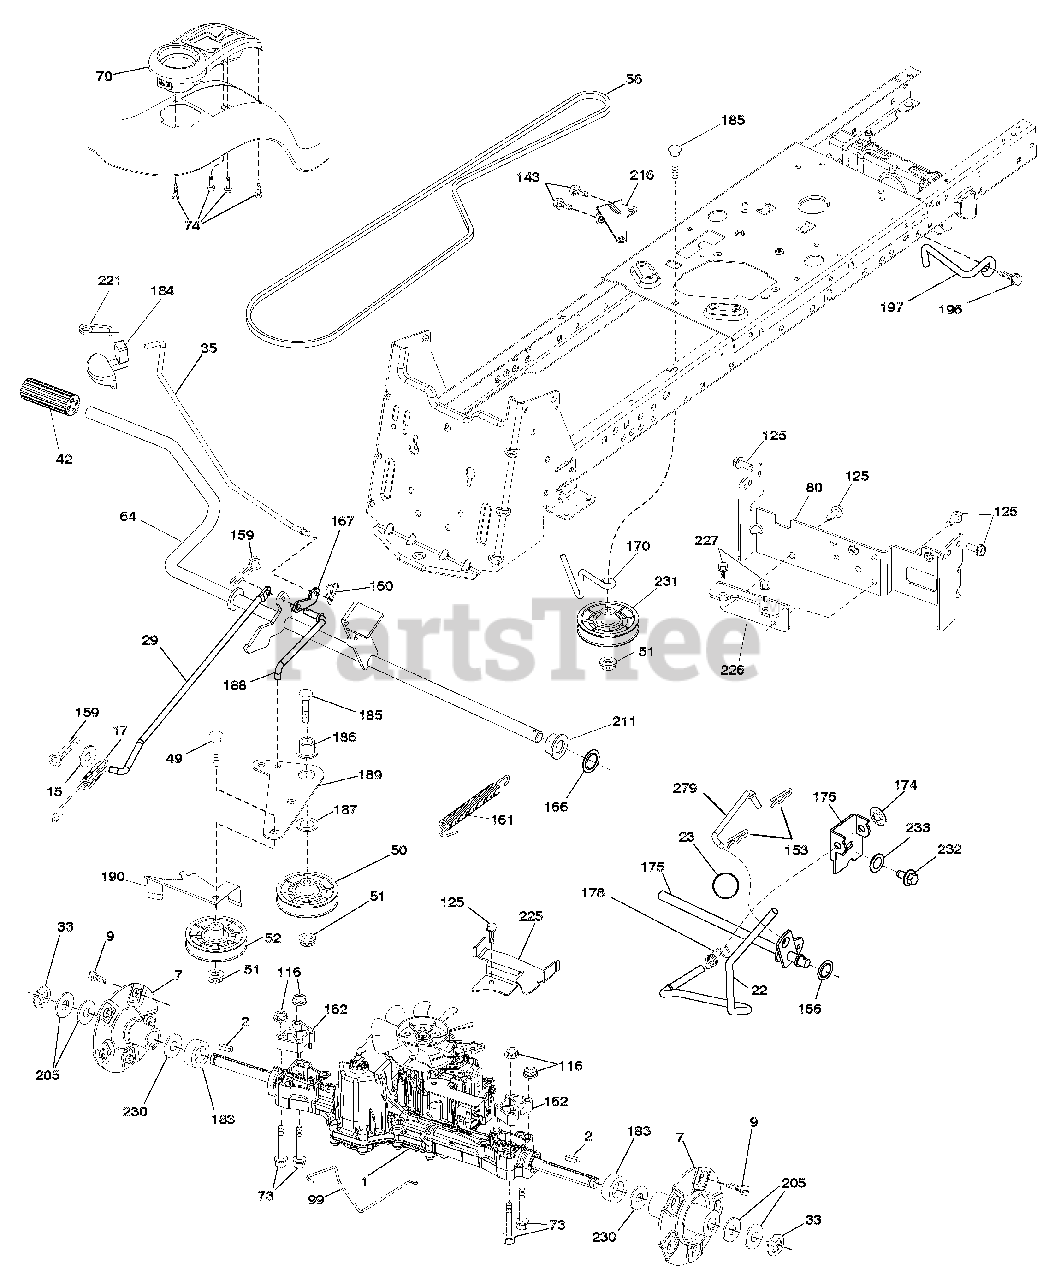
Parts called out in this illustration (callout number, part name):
1	TRANSAXLE, TUFFTORQ TTK46AW (448354) (ORDER PARTS FROM TRANSAXLE MANUFACTURER.)
7	HUB.ASM.WHEEL
9	BOLT HUB WHEEL
15	WASHER.13/32 X 13/16 X 16 GA.
17	SPRING.BRAKE.K46.GREEN
22	ROD.SHIFT
23	KNOB DELUXE
29	ROD.BRAKE.K46
33	E-RING.#5133-75
35	ROD.BRAKE.PARKING.LT.TEX
42	COVER PEDAL BLK ROUND
49	BOLT.RDHD.3/8-16UNCX1-3/4.GR5
50	IDLER.FLAT.910"OFFSET
51	Nut, Hex, Flangelock 3/8-16
52	IDLER.V-GROOVE.910"OFFSET
56	V-BELT.MOWER.92.40.42/K46
64	SHAFT ASM.PEDAL.BRAKE CONTROL
70	CONSOLE.SHIFT STL.HYD.BLACK.TX
73	BOLT 5/16-18
74	SCREW.HEX.WSH.HI-LO.1/4X1/2UNC
80	STRAP.TORQUE.K46/18"TEX
99	ROD.BYPASS
116	Nut, Lock Hex Flange 5/16-18 u
125	SCREW.5/16-18X3/4.SMGML.TAP/BL
143	SCREW.THDROL.5/16-18 X 1/2TYTT
153	RETAINER SPRING
159	PIN.COTTER.1/8 X 3/4.CAD.
160	RETAINER.CLIP(M).DIA.290
161	SPRING.RETURN.CLUTCH.6.75
162	SPACER.TRANSAXLE
166	NUT PUSH .625
167	LATCH.BRAKE.PARKING
170	KEEPER.CENTER SPAN.1.688
174	NUT.PUSH..500
175	SHAFT ARM SHIFT
176	ARM.CLEVIS.ROD.SHIFT
178	SPRING.SHIFT.GT.2006
183	SPACER.AXLE
184	HANDLE.PARKING.BRAKE
185	BOLT.RDHD.3/8-16UNC X2-3/4 GR5
186	SPACER.RETAINER
187	WASHER.13/32 X 2 X 10 GA.
188	LINK.CLUTCH.GROUND DRIVE
189	BELLCRANK.GROUNDRIVE.NSTG/NSTL
190	KEEPER.BELLCRANK.DRIVE.GROUND
196	SCREW.3/8-16X1.SMGML.TAP/R.BLK
197	LINK CLUTCH ANTI-ROTATION
205	WASHER.25/32 X 1-5/8 X 16GA.
211	BUSHING.SHAFT.BRAKE.HAND CONTR
216	BRACKET.PULLEY.IDLER.WTEX
221	RETAINER.SPRING.CLIP.HANDLE
225	KEEPER.BELT.TRANSAXLE.K46
226	BRACKET.MOUNT.TORQUE
227	SCREW 5/16-18 X 3/4
230	WASHER.HARDEN..793 X 1.637X060
231	IDLER.V-GROOVE.1.688"OFFSET
232	BOLT.FIN HEX.7/16-14X1 GR5
233	WASHER.SERRATED
279	LINK SHIFT T/A
